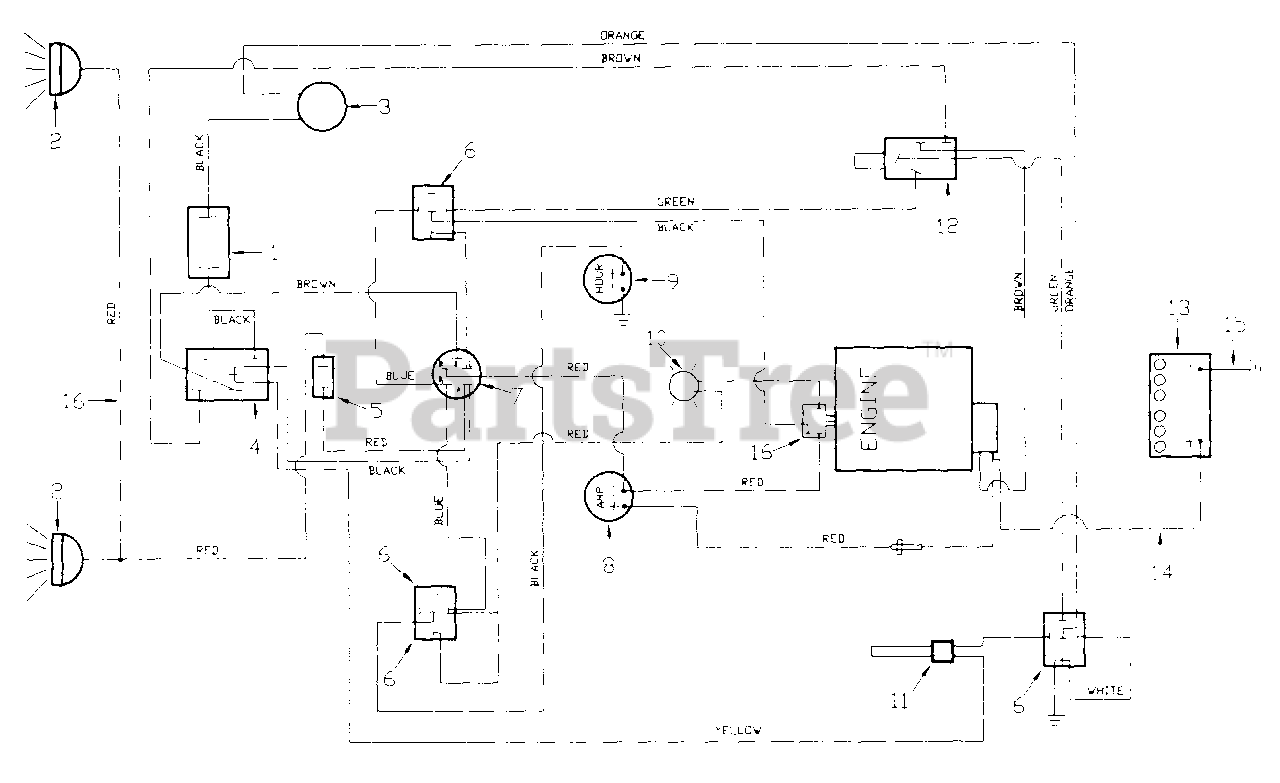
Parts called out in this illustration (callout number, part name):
1	10 Amp Circuit Breaker
2	Headlight Assembly
3	Electric Clutch Assembly
4	PTO Clutch Switch
5	Light Switch
6	Relay
7	Ignition Switch (Onan)
13	Battery
